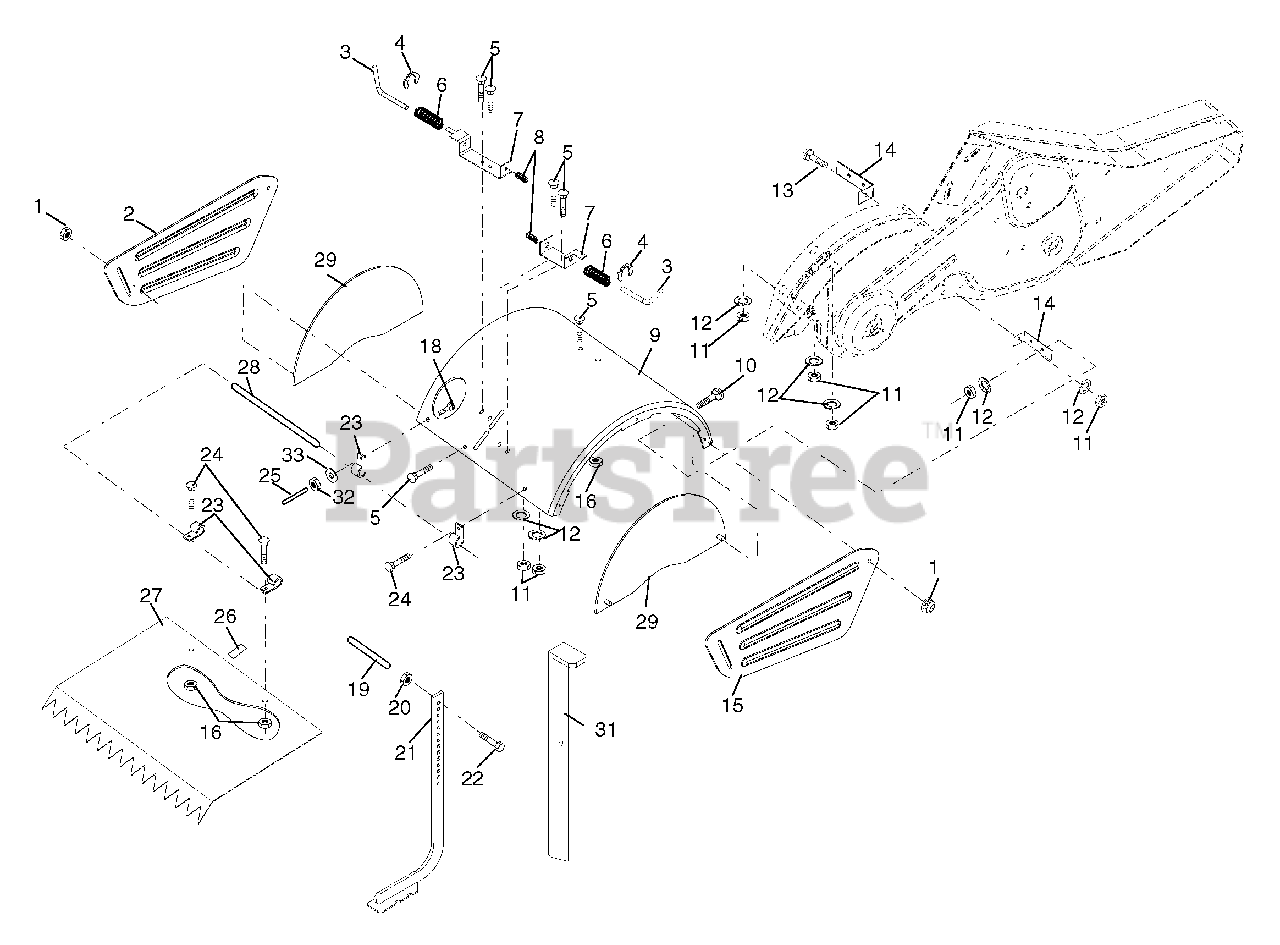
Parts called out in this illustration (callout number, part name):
1	Nut, Lock Hex Flange 5/16-18 unc
2	Shield, Side, Outer L. H.
3	Pin, Stake, Depth
4	Ring, Klip
5	Bolt Rdhd Sqnk 5/16-18 x 3/4
6	Spring
7	Bracket, Latch
8	Spring, Depth Stake
9	Shield, Tine
10	Bolt 5/16-18 x 1
11	Washer, Lock 5/16
12	Nut, Hex 5/16-18
13	Bolt, Carriage 5/16-18 x 1-1/4
14	Bracket, Shield Tine
15	Shield, Side, Outer R.H.
16	Nut, Hex Flange 1/4-20
17	Nut, Wing Forged 5/16-18
18	Bolt, Carriage 1/4-20 x 1-1/4 Gr. 5
19	Grip
20	Nut, Hex 3/8-16
21	Stake, Depth
22	Bolt, Hex 3/8-16 x 2
23	Hinge
24	Bolt, Carriage 1/4-20 x 1/2
25	Cap, Vinyl
26	Pad, Idler
27	Shield, Leveling
28	Pin, Hinge
29	Shield, Side
31	Stake, Drag
32	Nut, Fin, Hex 1/4-20 unc
33	Washer Lock Hvy Helical 1/4
